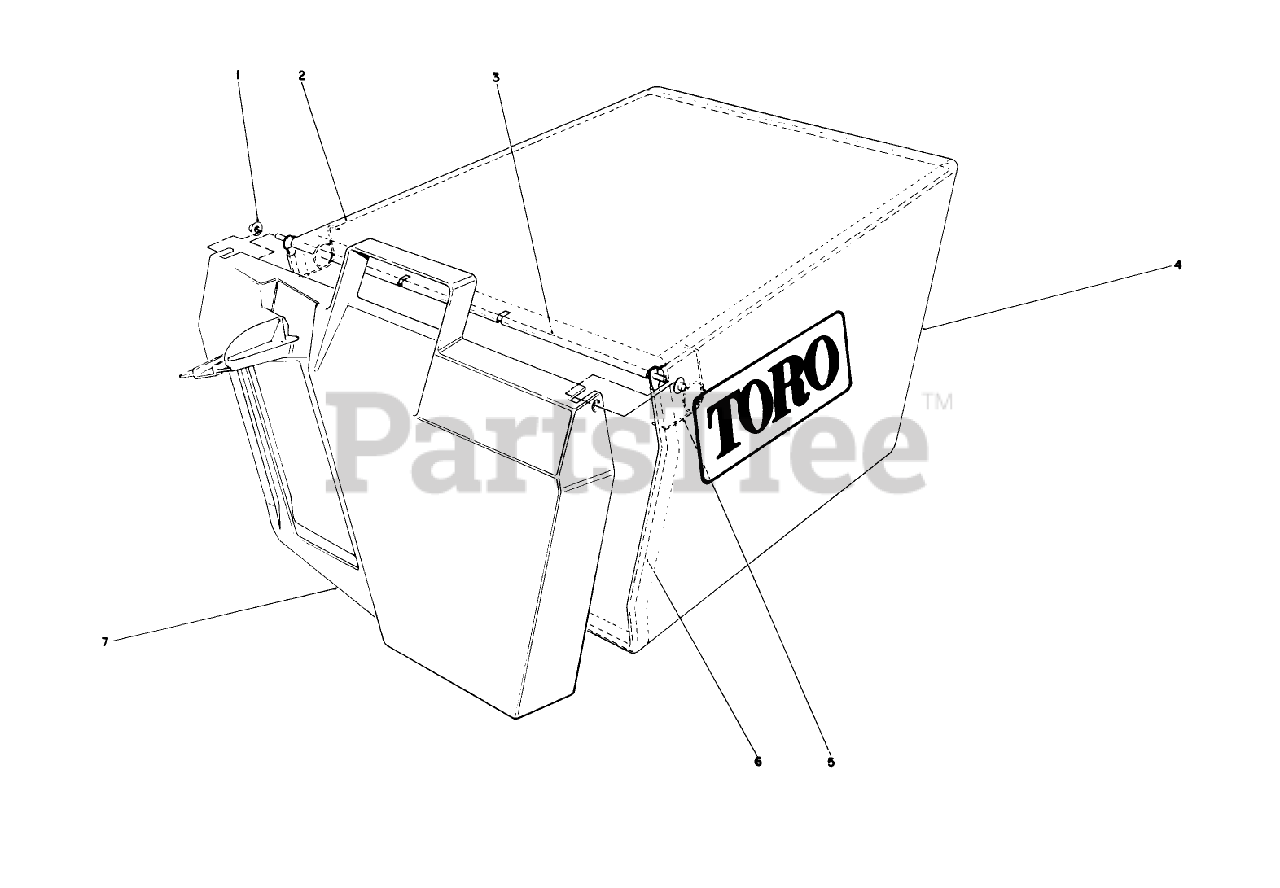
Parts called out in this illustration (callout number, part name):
1	NUT-PUSH
3	HINGE-DOOR, BAG
4	BAG-GRASS
5	SPRING
7	BAG DOOR
